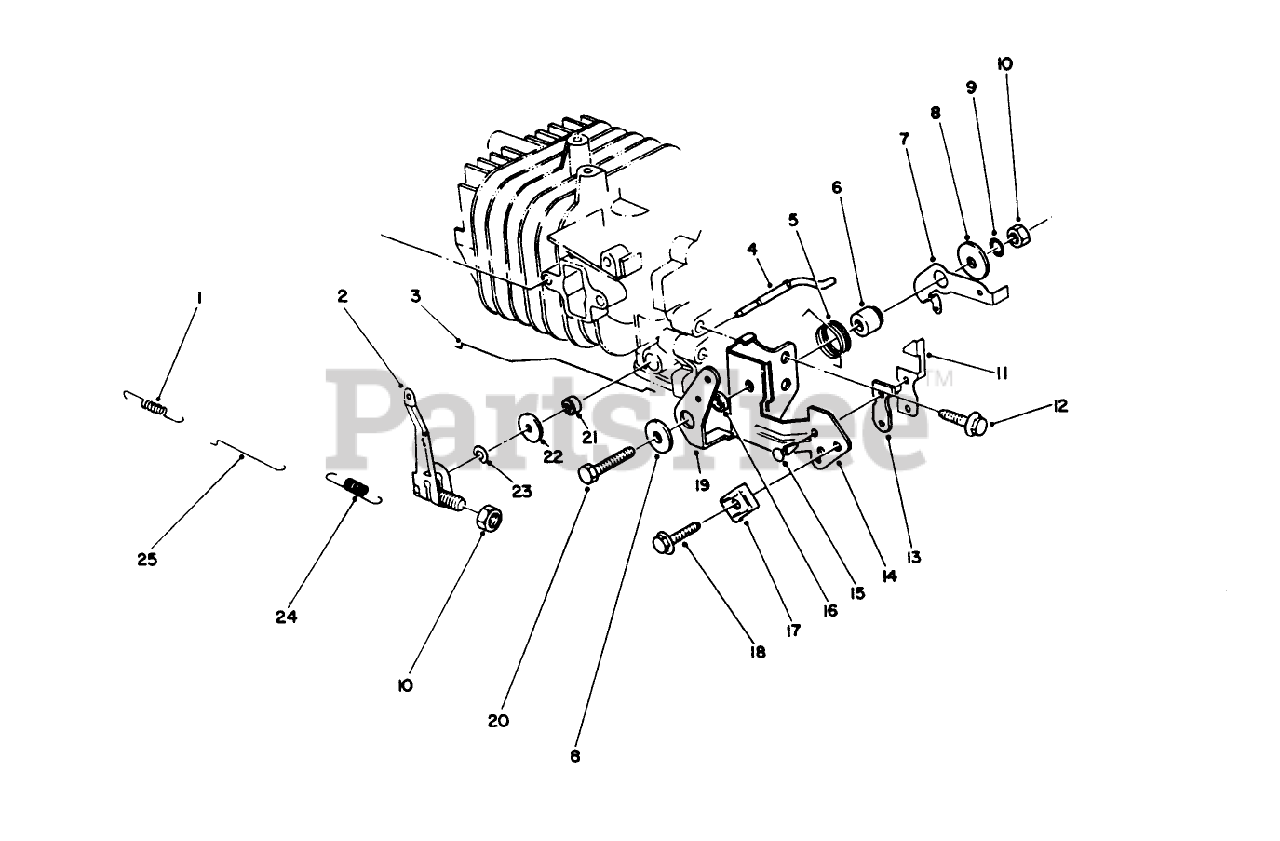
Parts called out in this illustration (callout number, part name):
1	SPRING
5	SPRING-CHOKE LEVER
7	LEVER-SPRING, GOVERNOR
8	WASHER
9	LOCKWASHER
11	TERMINAL-KILL SWITCH
13	INSULATOR-KILL SWITCH
14	BRACKET-THROTTLE, CONTROL
16	SPACER-CHOKE LEVER
17	CLAMP
21	SEAL-OIL
22	WASHER
24	SPRING-GOVERNOR
25	ROD-CARBURETOR
